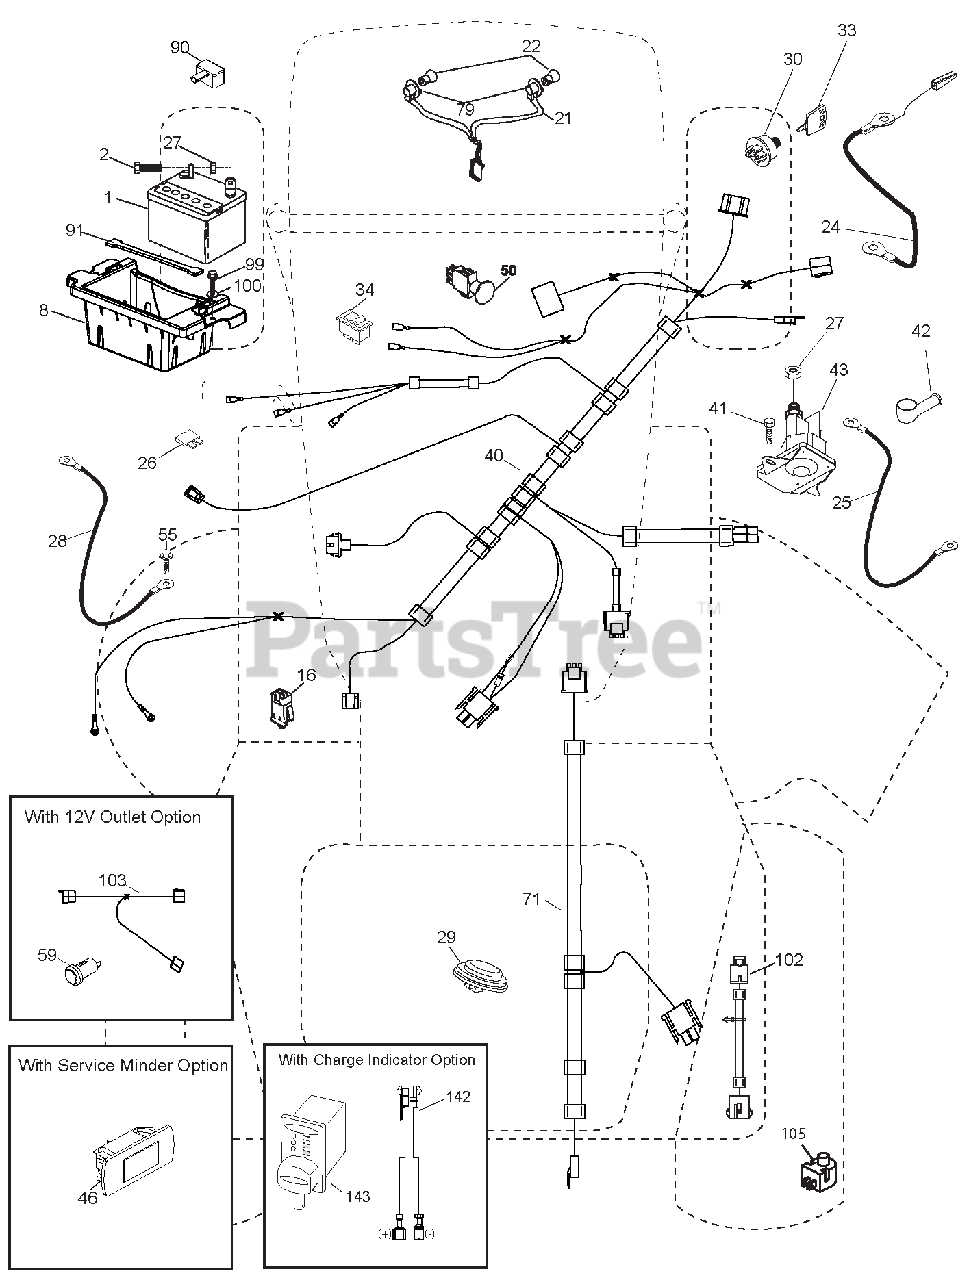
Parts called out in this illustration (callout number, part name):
1	BATTERY.12.VOLT.28.AMP.WET
2	BOLT.HEX.HD.1/4-20UNC X 3/4
8	BOX.BATTERY.MOUNT.FRONT.LT
16	SWITCH.INTERLOCK.NONO.GRAY
21	HARNESS ASM.LIGHT.22"(4152J)
22	BULB.LIGHT.#1156
24	CABLE.BTRY.PSWRE.DSH SOL.8"TEX
25	CABLE STARTER 6 G4. BL/RED14.5
26	FUSE.20 AMP.
27	Nut, Keps Hex 1/4-20 unc
28	CABLE.GROUND.21"BLK.6 GA.90T
29	SWITCH.SEAT.DELTA.OPC.9LB.
30	SWITCH.IGN.DLTA.P-IN.ROS
33	KEY/CHAIN.BLISTER PACK.GEN.USA
34	SWITCH.LIGHT/RESET.B/B/RED.
40	HARNESS.IGN.DASH.HUSQ/PRED.
41	Screw 1/4-20 x 1/2
42	COVER.TERMINAL.RED
43	SOLENOID.W/BRASS PLUNGER.2005
46	HOUR METER
50	SWITCH.PTO.8 TERMINAL.BLACK
55	SCREW.5/16-18X3/4.SMGML.TAP/R
71	HARNESS.IGN.CHASSIS.TEX
79	SOCKET ASM.BULB.TWISTLOCK
90	COVER TERMINAL BATTERY FR. TEX
91	STRAP.BATTERY.MOUNT.FRONT
99	SCREW.HEXWSH.THDROL.1/4-20X3/4
100	WASHER.9/32 X 7/8 X 16GA.
102	HARNESS.PIGTAIL.K46.TEX.ROS
105	SWITCH.REVERSE.TT.PEDAL CONTRO
